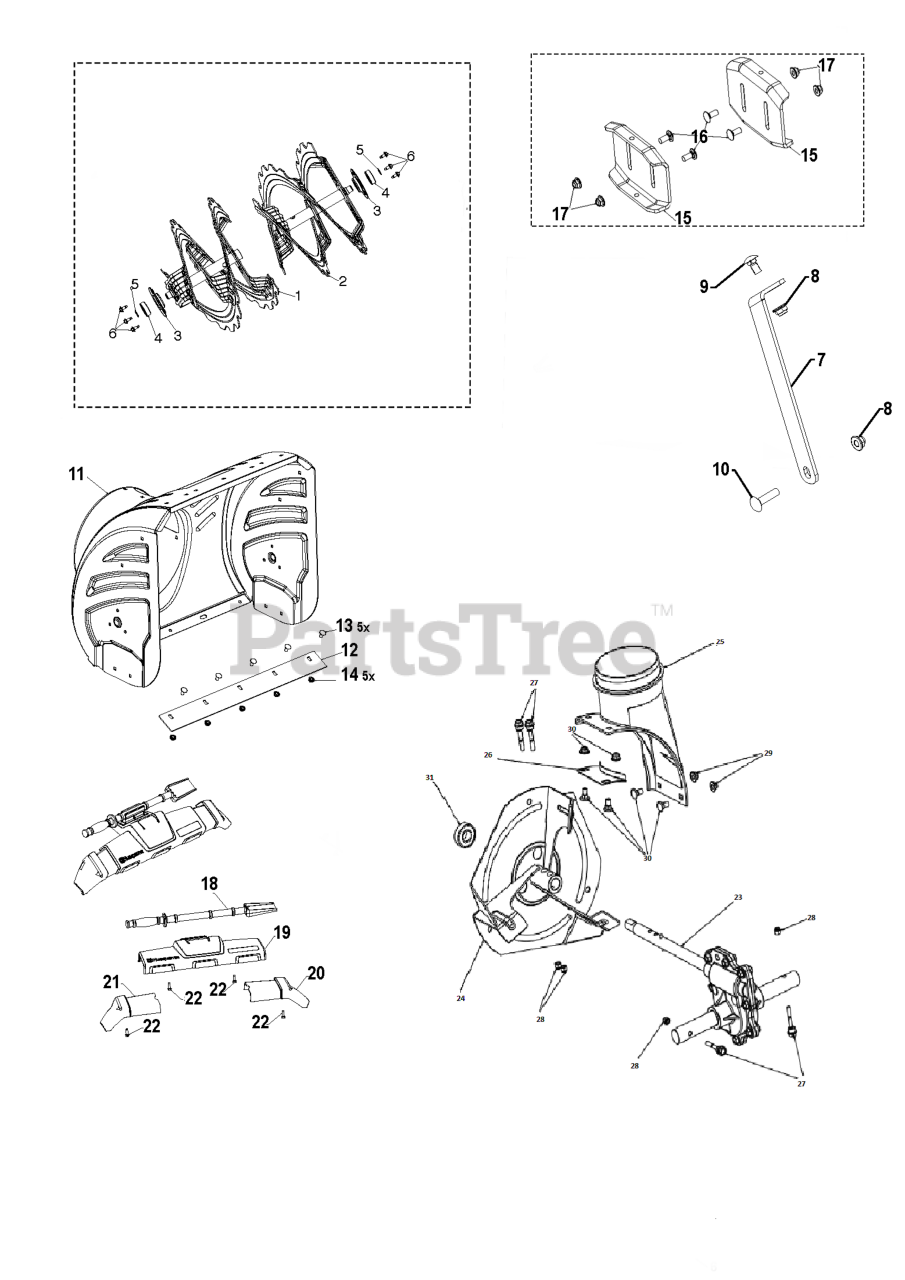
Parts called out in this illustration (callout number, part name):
1	AUGER.RIB.24.RH.LS.GREY
2	AUGER.RIB.24.LH.LS.GREY
3	SUPPORT.BEARING.SINGLE.STAGE.B
5	RETAINING RING LT
6	HEX.WASHER.HEAD 1/4-20 X .65
7	SUPPORT.GEARBOX.LS.498
8	NUT HEX FLG NYLOCK BLK 5_16-1
9	BOLT CAR BLK 5/16-18 X 5/8
10	NUT HEX FLG NYLOCK BLK 5_16-1
10	BOLT.CARRIAGE.5/16-18
11	HOUSING ASSY KIT 586184202 AU
12	PLATE.SHAVE.24.LS.SNOW.BLACK
12	PLATE.SHAVE.27.LS.SNOW.BLACK
13	BOLT ROUND HEAD SQUARE NECK BO
14	GSPW Hardware
14	NUT.FLANGE.5/16
15	SKID PLATE
16	BOLT CARR BLK 5_16-18 X .750
17	NUT HEX FLG NYLOCK BLK 5_16-1
18	CLEAN OUT TOOL
19	TRIM AUGER FRONT TRIM ASSEMBLY
20	TRIM AUGER.HOUSING.WING.RH MS
21	TRIM AUGER.HOUSING.WING.LH MS
22	SCREW 14-20 X 5/8
23	GEARBOX ALUM. DD FUSED
23	GEARBOX CAST DD SHAFT
24	IMPELLER.STEEL.SNOW.BLACK
24	IMPELLER CAST.IRON.12IN MS 417
25	CHUTE.DISCHARGE.BASE
27	BOLT SHEAR HX HD 1/4-20 CLEAR
28	NUT HEXAGON 1/4-20 ST ZPB
29	NUT HEX FLG NYLOCK BLK 5_16-1
30	BOLT CARR WAFER BLK 5_16-18 X
